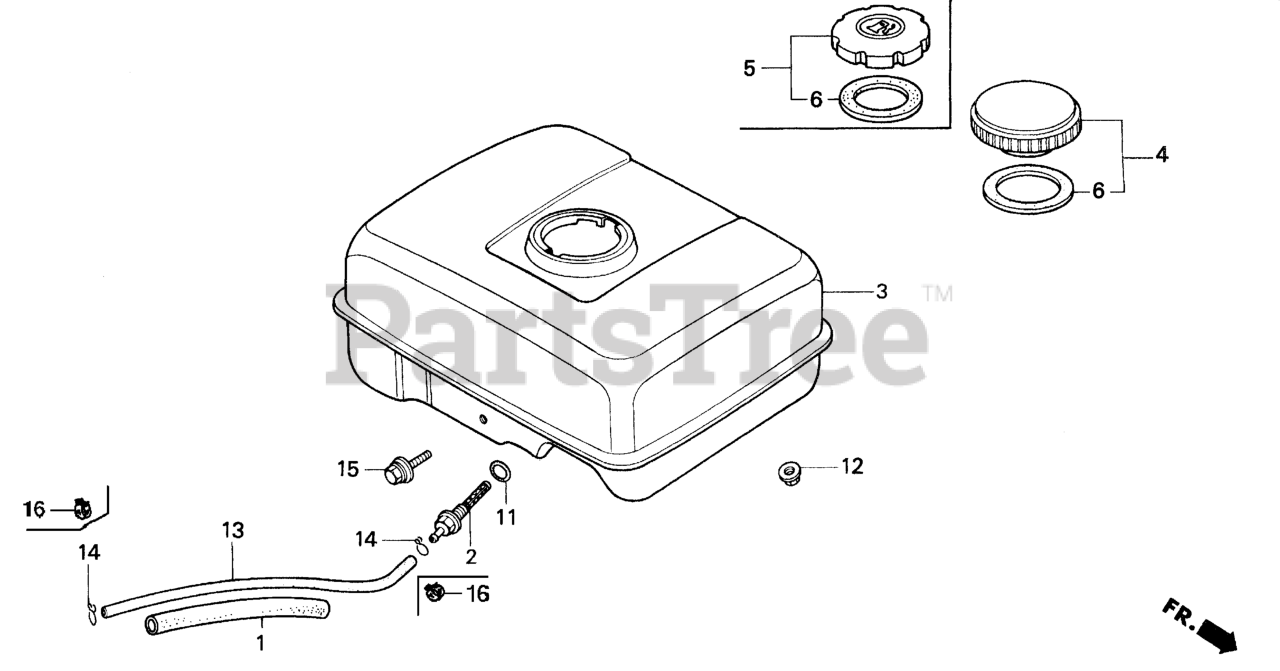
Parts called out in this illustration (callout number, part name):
1	RUBBER, SUPPORTER (107MM)
2	JOINT, FUEL TANK
3	TANK, FUEL *NH1* (BLACK)
3	TANK, FUEL *NH31* (MCKINLEY WHITE)
4	CAP, FUEL FILLER Use from Engine SN 1211508 to 1518838.
4	CAP, FUEL FILLER
5	CAP, FUEL FILLER (BLACK) Use up to Engine SN 2115700.
5	CAP, FUEL FILLER (CHROME PLATED)
5	CAP COMP
6	GASKET, FUEL FILLER CAP (39X58X3) (NOT AVAILABLE)
6	GASKET, FUEL FILLER CAP Use from Engine SN 1543258.
6	GASKET, FUEL FILLER CAP (39X58X3)
11	O-RING (14MM) (ARAI) Use up to Engine SN 2949254.
12	NUT, FLANGE (6MM)
13	BULK HOSE, FUEL (4.5X3000) (Honda Code 5137104). (4.5X140)
14	CLIP, TUBE (B8)
15	BOLT, FLANGE (6X25)
